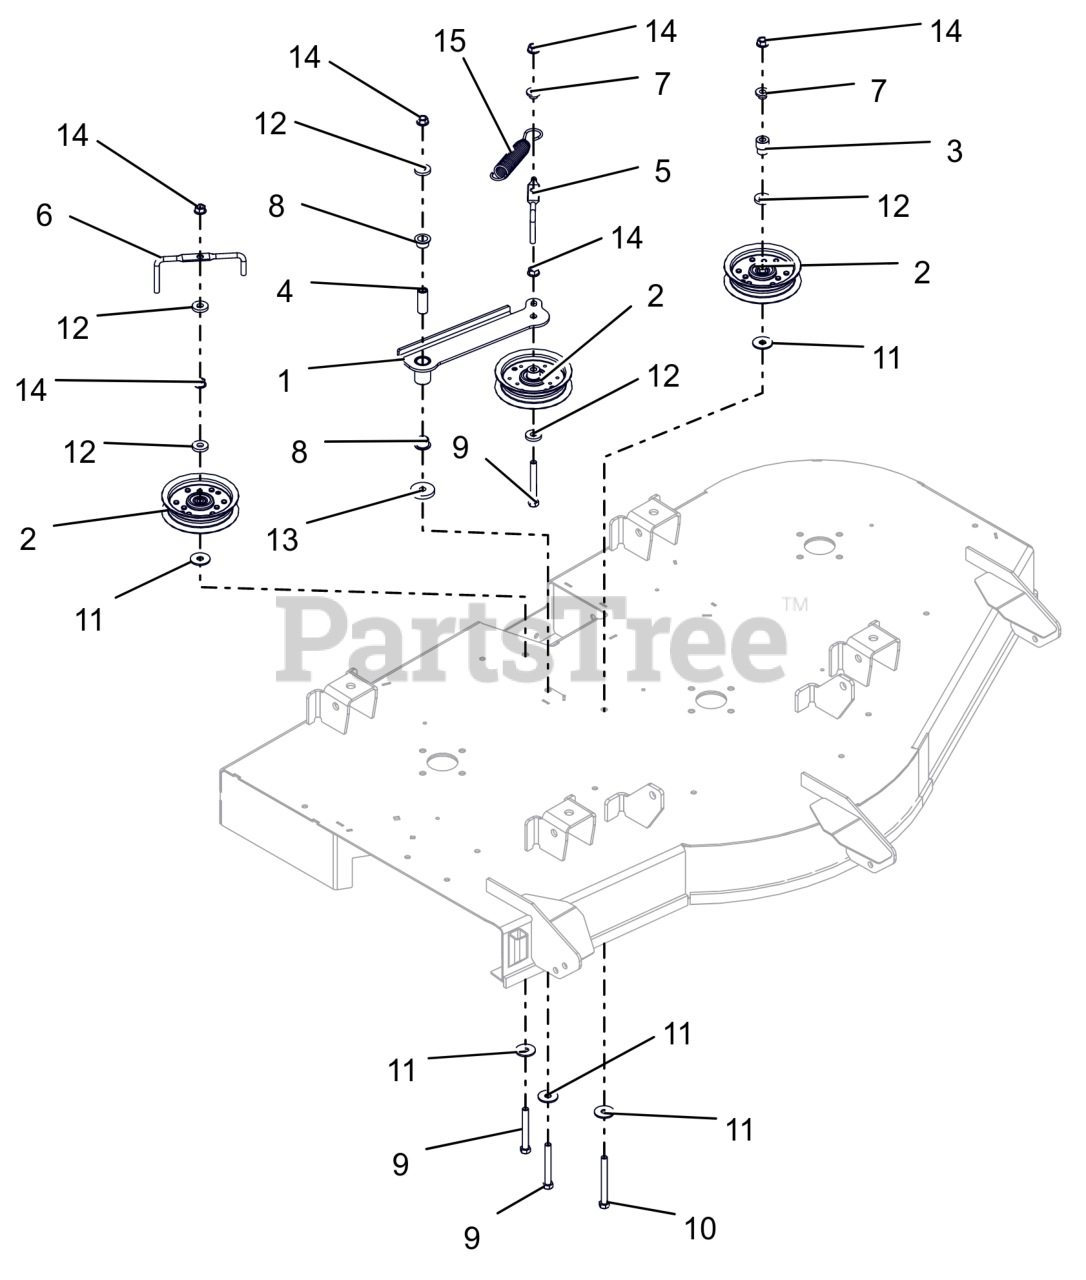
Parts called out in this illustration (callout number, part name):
1	WLDMT, IDLER ARM-52"
2	ASM, IDLER 4"
3	BUSHING, IDLER (P/M)
4	SPACER, .375IDX.625ODX1.66 PM
5	WIREFORM, BELT FINGER
6	WIREFORM, BELT FINGER
7	BSHG-FLG .385X.500X.875X.406
8	BSHG-FLG, .625X.750X.500X1.00
9	BLT, HEX .38-16X3.00F G5 ZCC
10	BLT, HEX .38-16X3.50 G5 ZCC
11	WSHR FL STL .406X1.25X.10ZC120
12	WSHR, FLT .406X1.00X.188 ZCC
13	WSHR, FLT .406X1.50X.245 ZCC
14	NUT-LK-CTR-FLG .375-16 GF ZCC
15	SG-TENS .135X.98X6.0 WLD 62
